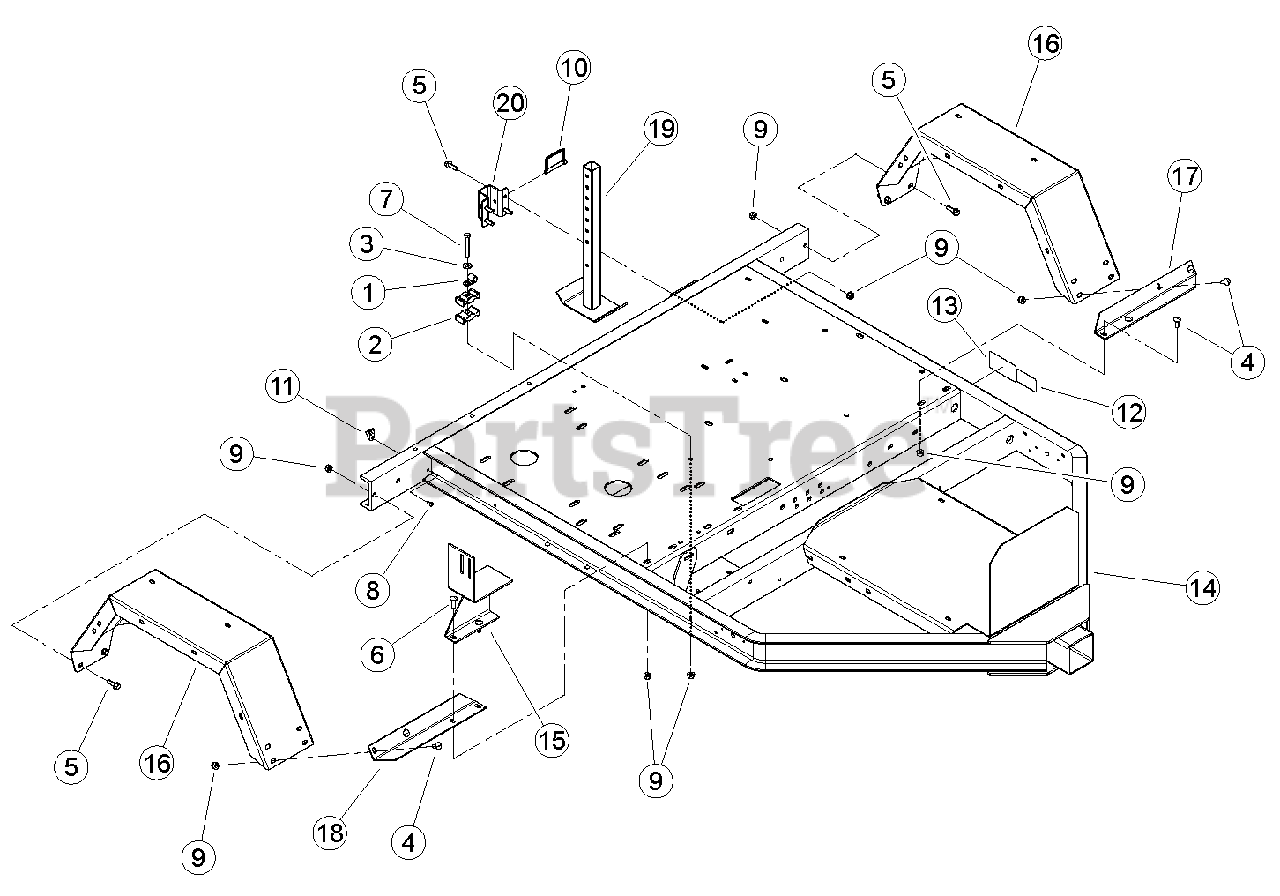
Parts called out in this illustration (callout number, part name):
1	CLAMP, 9/16 COATED
2	CLAMP, PLASTIC HOSE
3	WASHER, 3/8" FLAT ZP
4	BOLT, 3/8 X 1" GR5 CRG NC ZP
5	BOLT, 3/8 X 1-1/4 FLANGE NC
6	BOLT, 3/8 X 1-1/4" GR5 CRG NC ZP
7	BOLT, 3/8 X 2-3/4" GR5 NC HHCS ZP
8	RIVET, AL BLIND 1/4 X 3/4 DOME HEAD
9	NUT, 3/8-16 NYLOCK FLANGE
10	PIN, 3/8 X 2-3/4" SNAP
11	CLAMP, CABLE MOUNT
12	DECAL, P215/70R15 LOAD RATING
13	DECAL, EPA EMISSION
14	WELDMENT, CHIPPER TRAILER
15	WELDMENT, BELT GUIDE
16	FENDER, HEAVY DUTY
17	ANGLE, LH FENDER SUPPORT
18	ANGLE, RH FENDER SUPPORT
19	WELDMENT, REAR STABILIZER
20	GUIDE, TRAILER SUPPORT
